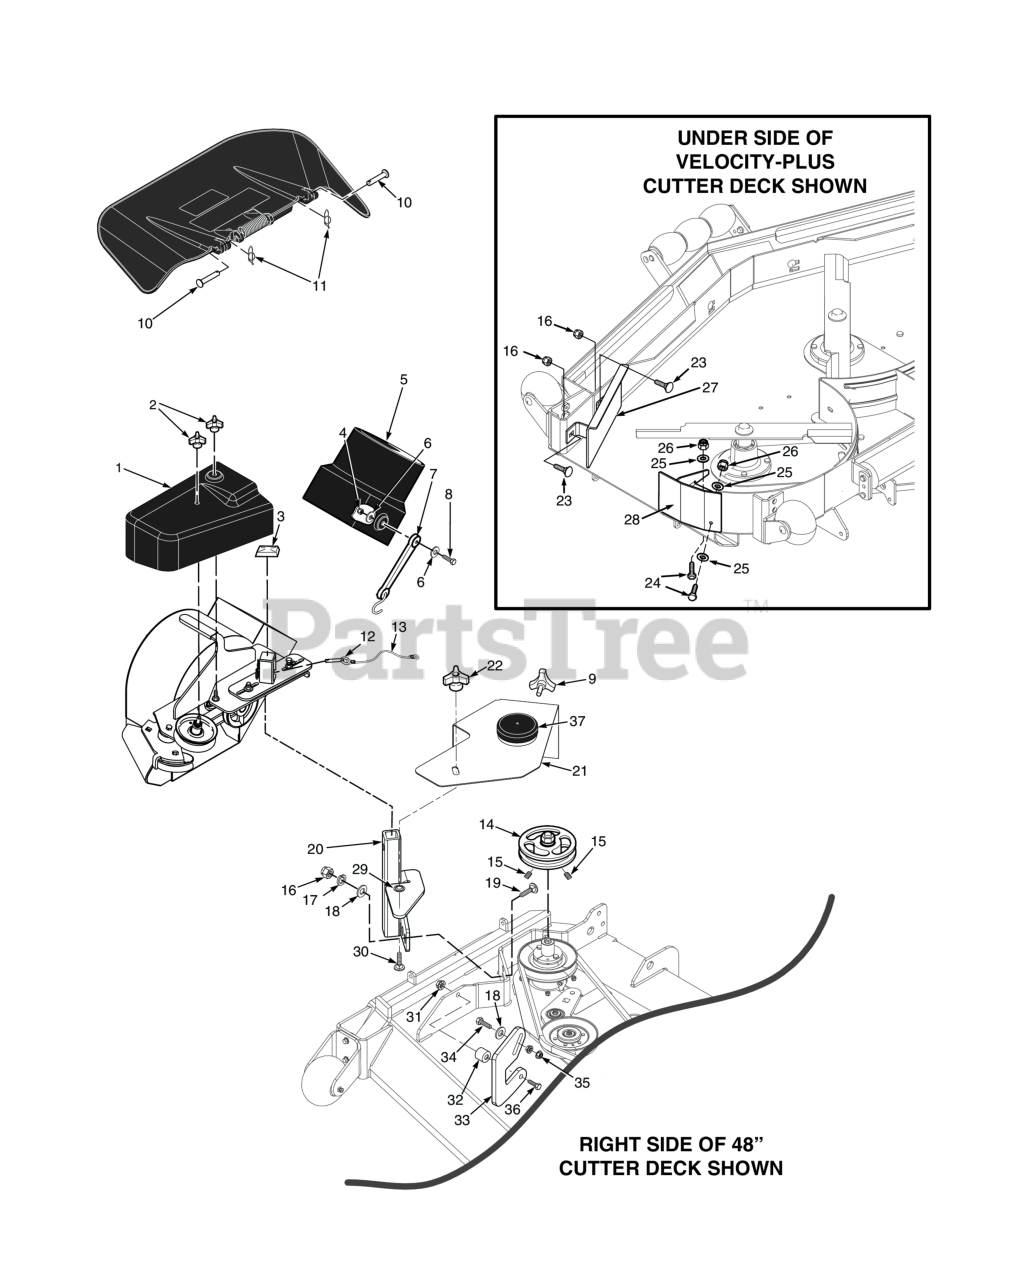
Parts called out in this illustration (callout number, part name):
1	Belt Cover, 48"
2	Wing Nut, 3/8-16 (Small) Top side
3	Cap, Square Vinyl
4	HEX, NUT, ELASTIC STOP LOCK, 1/4-20
5	Adapter, Blower GC-STC,
6	Flatwasher, 1/4" (.312 x .750 x .065")
7	Rubber Strap 7-3/4"
8	SERR. FLG. HEX HEAD CAPSCREW, 5/16-18 X 3/4
9	Knob, w/stud 3/8-16 x 1-1/4"
10	Clevis Pin, 5/16 x 1-1/2"
11	Pin, Rue Cotter 5/16 Dia.
12	Pin, Ring 1/2 x 2-1/4"
13	Lanyard, Deck Height Pin
14	Pulley, 4.0" Dia. - 1.125" Bore, (STT-52 & STTII-52)
15	Setscrew, Hex Socket Knurl Cup Pt. 5/16 - 18 (nylock)
16	HEX NUT, ELASTIC STOP LOCK, 3/8-16
17	Lockwasher, 3/8" Spring, Kawasaki FX / FT & FT-EFI / B&S 32BV
18	Flatwasher, 3/8" Special (.391 x .938 x .105)
19	SHORT SQ. NECK CARRIAGE BOLT, 3/8-16 X 1-1/4"
20	Mounting Post Weldment, Blower, (61")
21	Belt Cover Assembly, w/Cap - 48"
22	Wing Nut, 3/8-16 (Small) Top side
23	Carriage Bolt, 3/8-16 x 1.0"
24	Bolt, Heax Head 5/16-18 x 1" (48V / 52V)
25	Flatwasher, 5/16-.375 x .875 x .083 (35BV & 37BV-EFI)
26	HEX NUT, ELASTIC STOP LOCK, 5/16-18
27	Baffle Weldment, 52V Deck
28	Baffle, Turbo 48" Deck
29	Nut, Push-On - 3/8" Dia.
30	Carriage Bolt, 3/8-16 x 1-1/4"
31	NUT, 3/8-16 SERRATED FLANGE HEX HEAD
32	Spacer (STCII48 & SCZ48)
33	Bracket (STCII48 & SCZ48)
34	Bolt, Hex Head 3/8-16 x 1-1/2" Grade 8 Black
35	NUT, 3/8-16 SERRATED FLANGE HEX HEAD
36	Bolt, Hex Head 3/8-16 x 1-3/4" (Kohler EFI)
